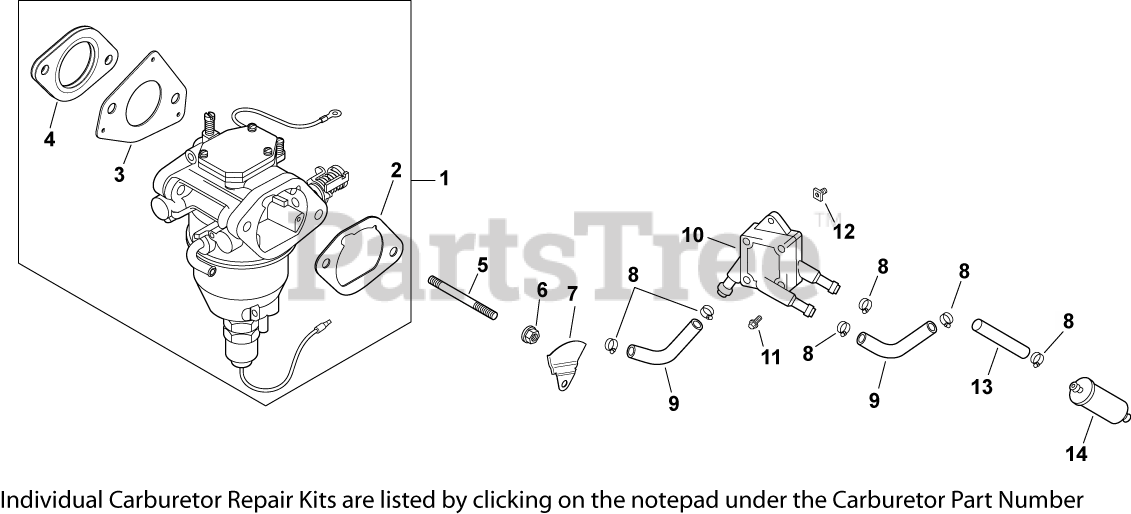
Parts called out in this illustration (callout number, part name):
1	KIT, CARBURETOR w/GASKETS
2	GASKET, AIR CLEANER BASE
3	GASKET, CARBURETOR
4	GASKET, CARBURETOR
5	STUD,M6X1.0X96
6	NUT, FLG M6X1.0
7	BAFFLE, SPIT-BACK CUP-USE 24 063 105-S
8	CLAMP, HOSE (KM)-USE 25 237 31-S
9	HOSE,LW PERM.FUEL 24.00"-USE 25 111 81-S
10	PUMP, FUEL
11	SCREW, TAP M6X1.7X18
12	NUT, PLASTIC - BLACK
13	LINE, FUEL 11"
14	FILTER, FUEL
